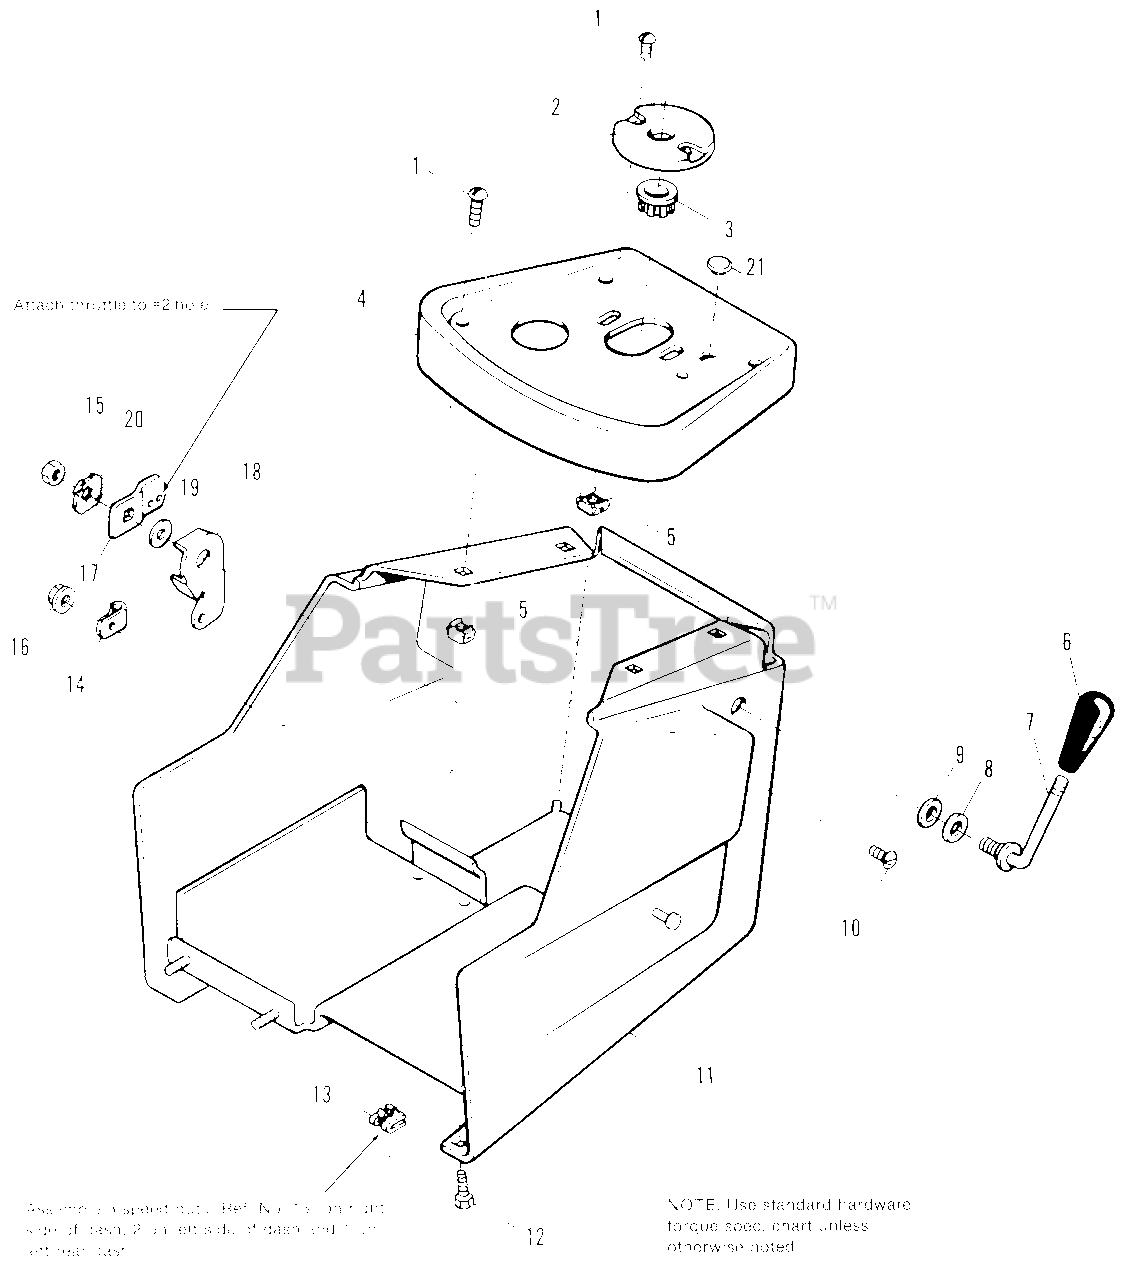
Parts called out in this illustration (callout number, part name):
1	SCREW, Machine, Rd. Hd., 1/4-20 x 12
2	PLATE, Adjusting, Steering
4	PANEL, Instrument
5	NUT, Tinnerman
6	KNOB
7	HANDLE, Clutch Control
10	SCREW, Round Hd., #10-32 x 1/2
12	SCREW, Hex, Self Tapping, #14AB x 3/4
13	NUT, Speed
14	CLIP, Bowden Wire
15	LOCKNUT, Hex, 3/8-16
16	NUT, Hex Washer, #10-32
17	ARM, THROTTLE
18	STOP, THROTTLE
20	LOCKWASHER, Dished Type, 3/8
21	PLUG, Button
